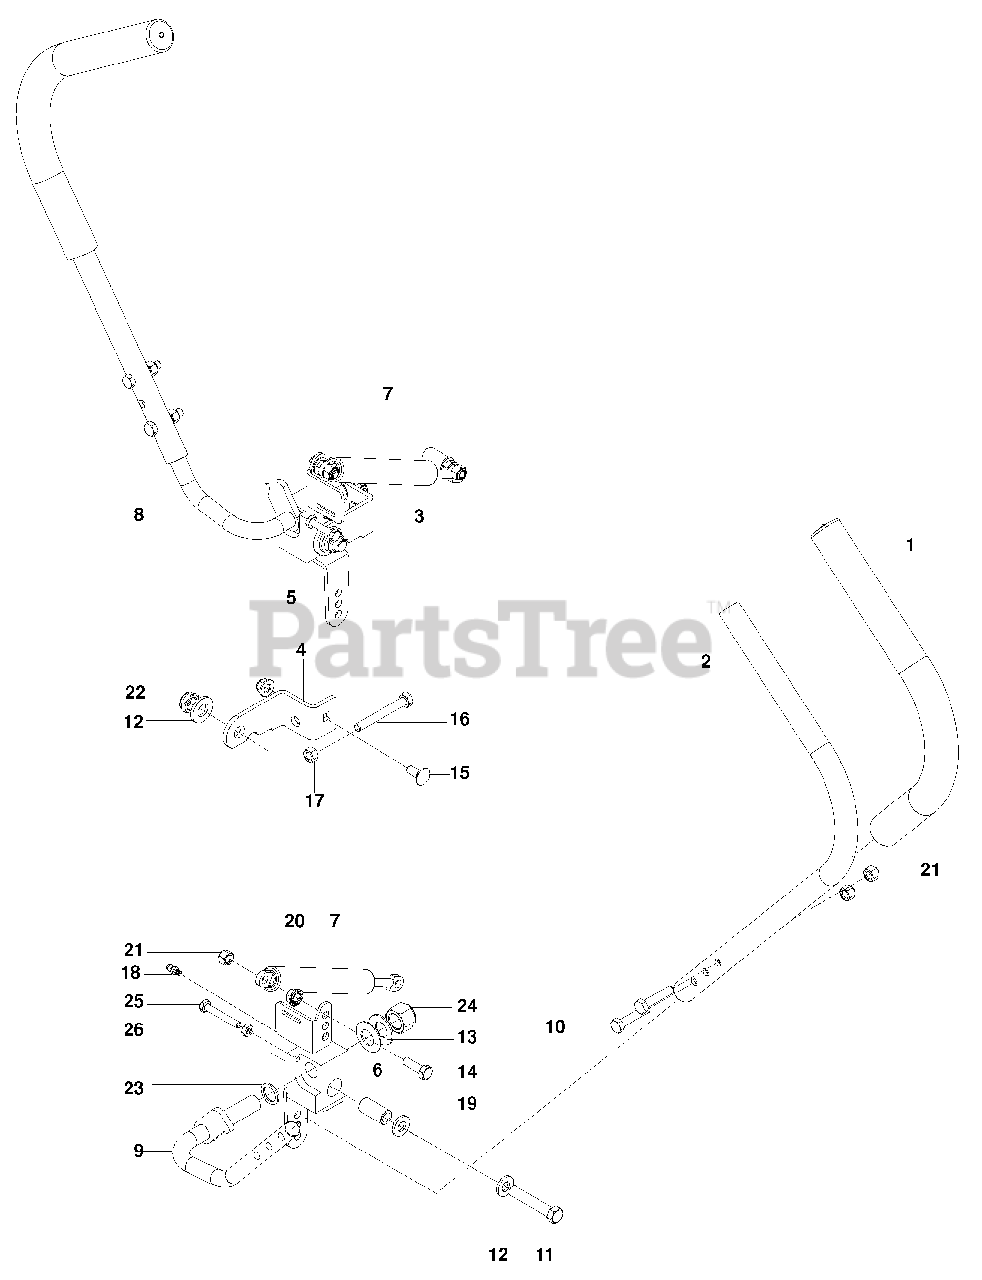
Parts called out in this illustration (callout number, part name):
2	LEVER, UPPER
3	STOP, STEER CNTRL RH
4	STOP, STEER CNTRL LH
8	LOWER LEVER, RH
9	LOWER LEVER, LH
10	HCS 5/16-18 x 1 1/2
11	HCS 1/2-13 x 2 3/4
12	WASHER 1/2 SAE
13	WASHER 5/8 BELLEVILLE
14	HCS 5/16-18 x 1
15	RHSNB 5/16-18 x 3/4
16	BOLT, HEX 5/16-18 x 2 1/2 TPBLT
17	NUT, 5/16-18 HEX
18	ZERK
19	BUSHING 1/2 ID x 3/4 OD
20	NUT 5/16-18 HEX WHIZLK
21	NUT 5/16-18 HEX NYLOC
22	NUT 1/2-13 JAM NYLOC GR 2
23	WASHER, SPECIAL
24	NUT 5/8-11 NYLOC
25	HCS 1/4-20 x 1 3/4
26	NUT 1/4-20 JAM
